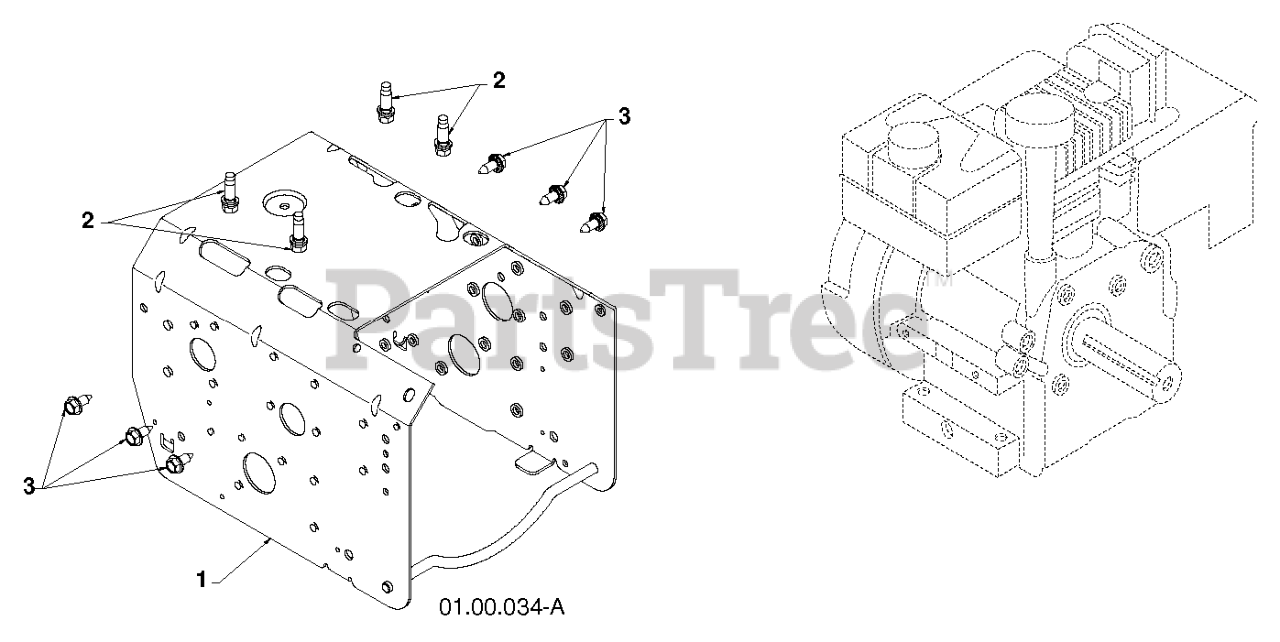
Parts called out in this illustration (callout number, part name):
1	FRAME.WELD.PNT.CHAIN.ORANGE
2	BOLT 3/8-16X1-1/8
3	BOLT.HEX.HD.WASHER.5/16-18X.75
